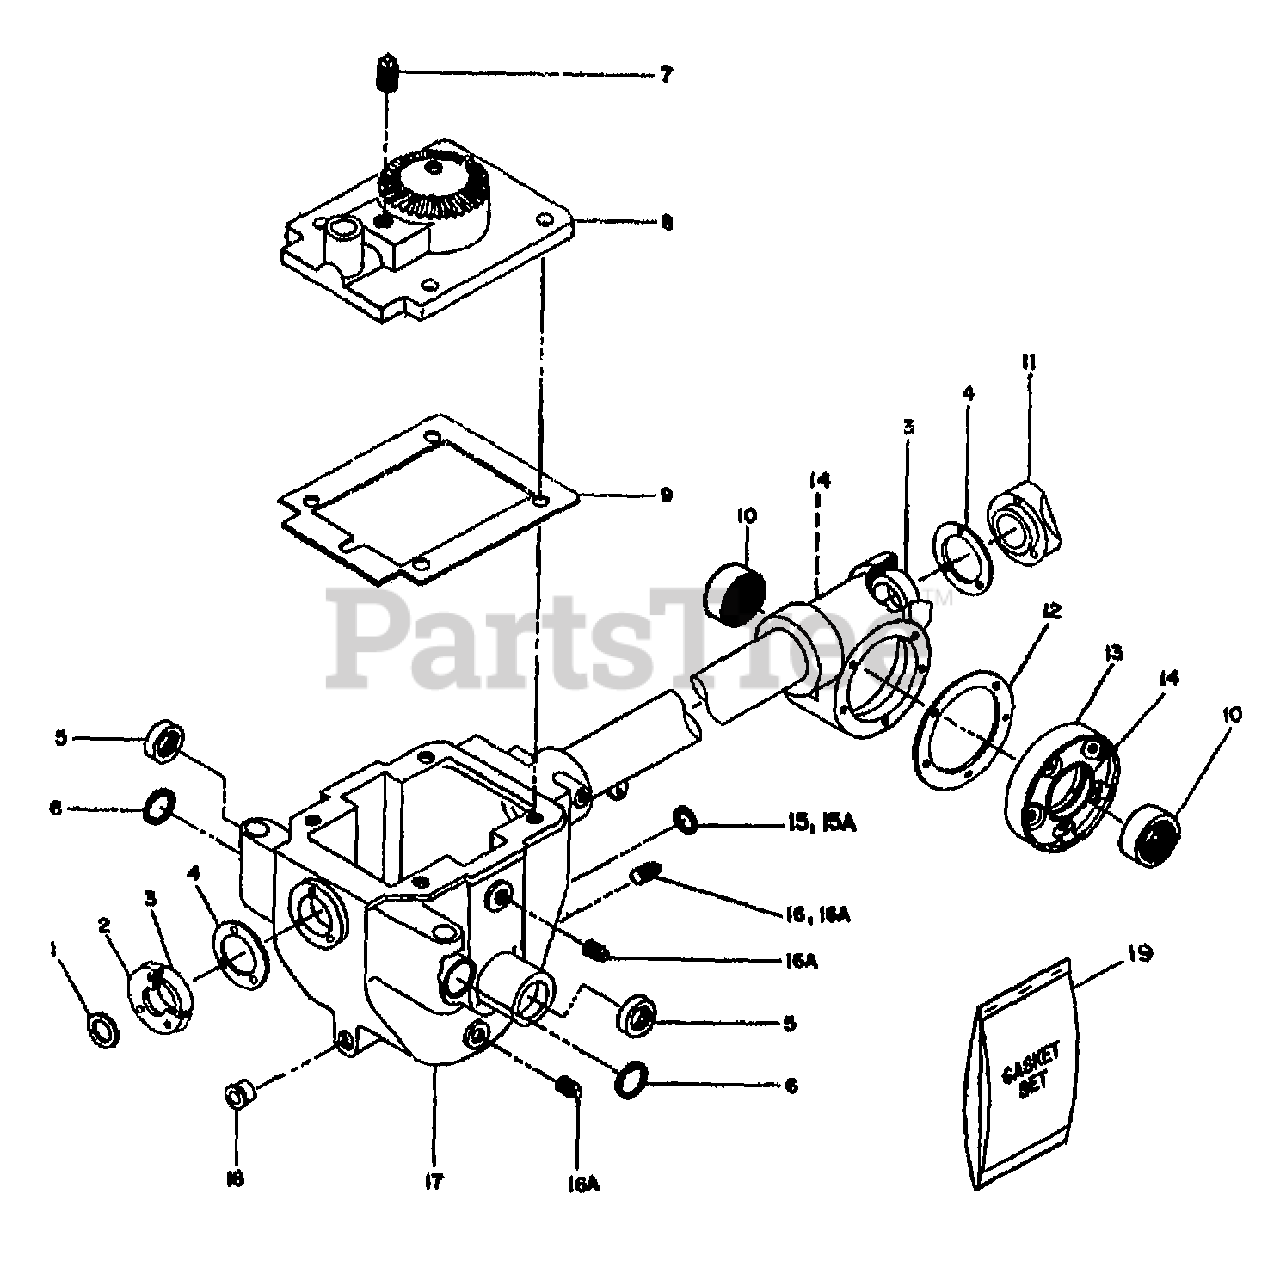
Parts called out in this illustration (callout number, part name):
1	SEAL-PINION SHAFT PT/85030/00
2	COVER-FRONT
3	KIT-BRG CONE&RACE-DRIVESHAFT
4	GASKET-BRG COVER
5	SEAL-OIL WHEELSHAFT
6	RING-O 1 ID
7	PLUG-PIPE 3/8 NPT
8	ASSM-COVER W/BOLT-HORSE
9	GASKET-TRANS COVER
10	SEAL-OIL TILLERSHAFT
11	CAP-REAR #1115
12	GASKET-TILLER COVER
13	COVER-W/SCRS(TLR) (9780)
14	KIT-TILLER GEAR & BRGS
15	SEAL-OIL ECCENTRIC
15A	RING-O .625 X .438
16	PLUG-PIPE 3/8 NPT
16A	PLUG-PIPE 1/4 NPT
17	CASE
18	PLUG-CAP (RED)
19	TRANS GASKET SET
